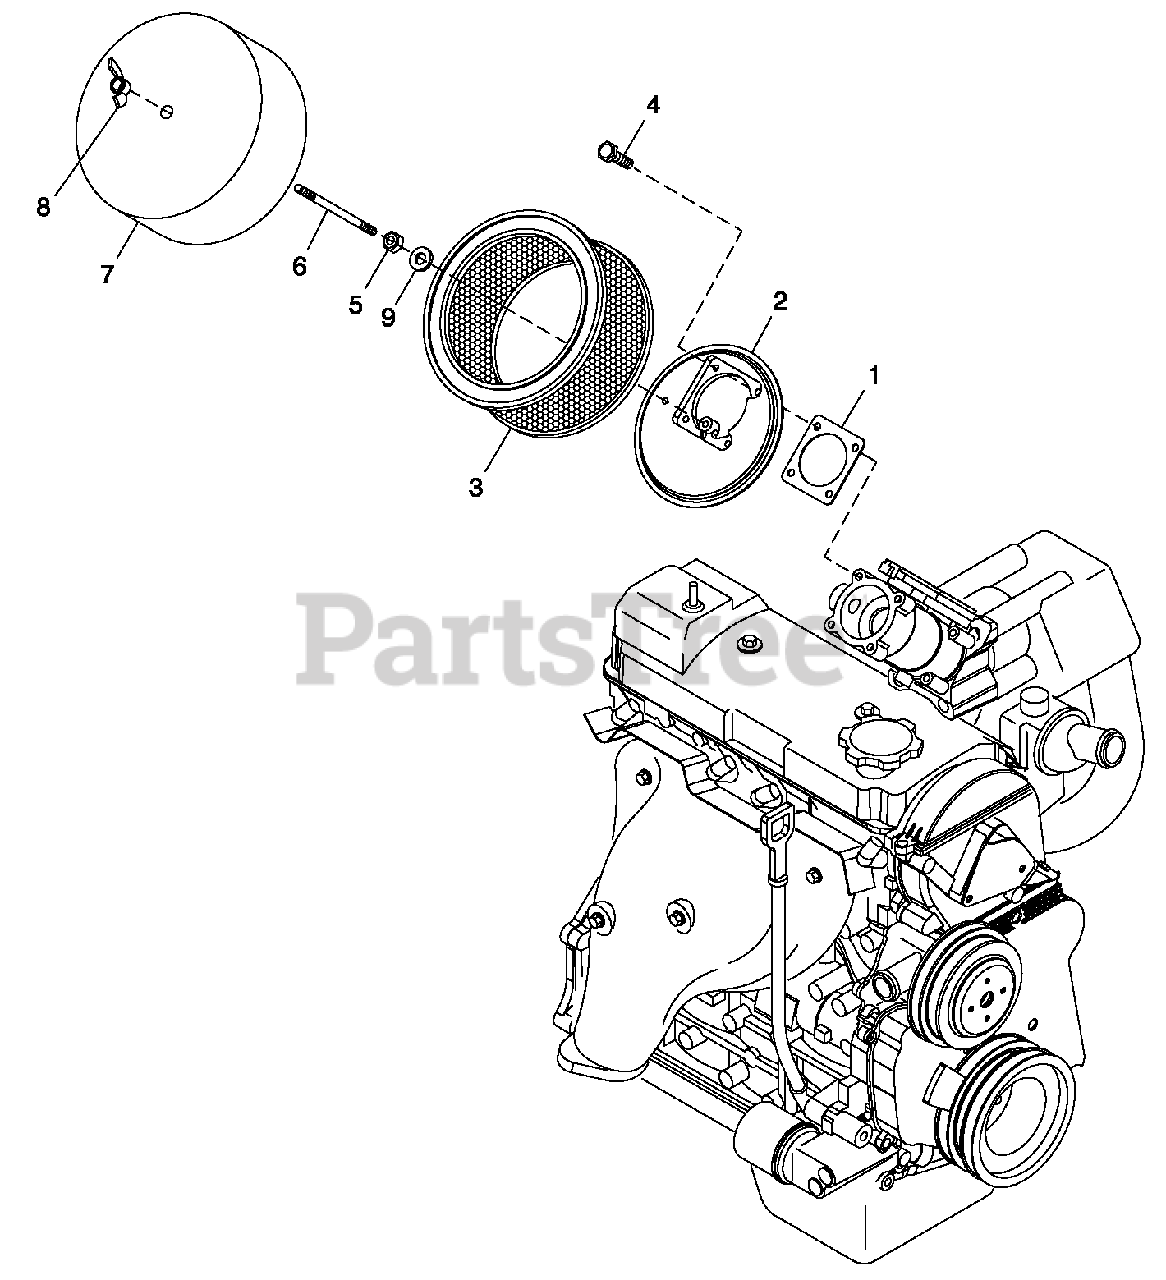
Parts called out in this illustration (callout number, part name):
1	GASKET BOSCH 32 & 40
2	ADAPTER CARBURETOR W/PVC CONN
3	ELEMENT AIR CLEANER
4	SCREW HHC M5-0.8 X 20 G8.8
5	NUT HEX 1/4-20 STEEL
6	STUD TH 1/4-20 X 4-1/2 G2 ZNC
7	PLATE, AIR CLEANER TOP 2.4L
8	NUT WING 1/4-20 NYLK
9	WASHER LOCK M6-1/4
